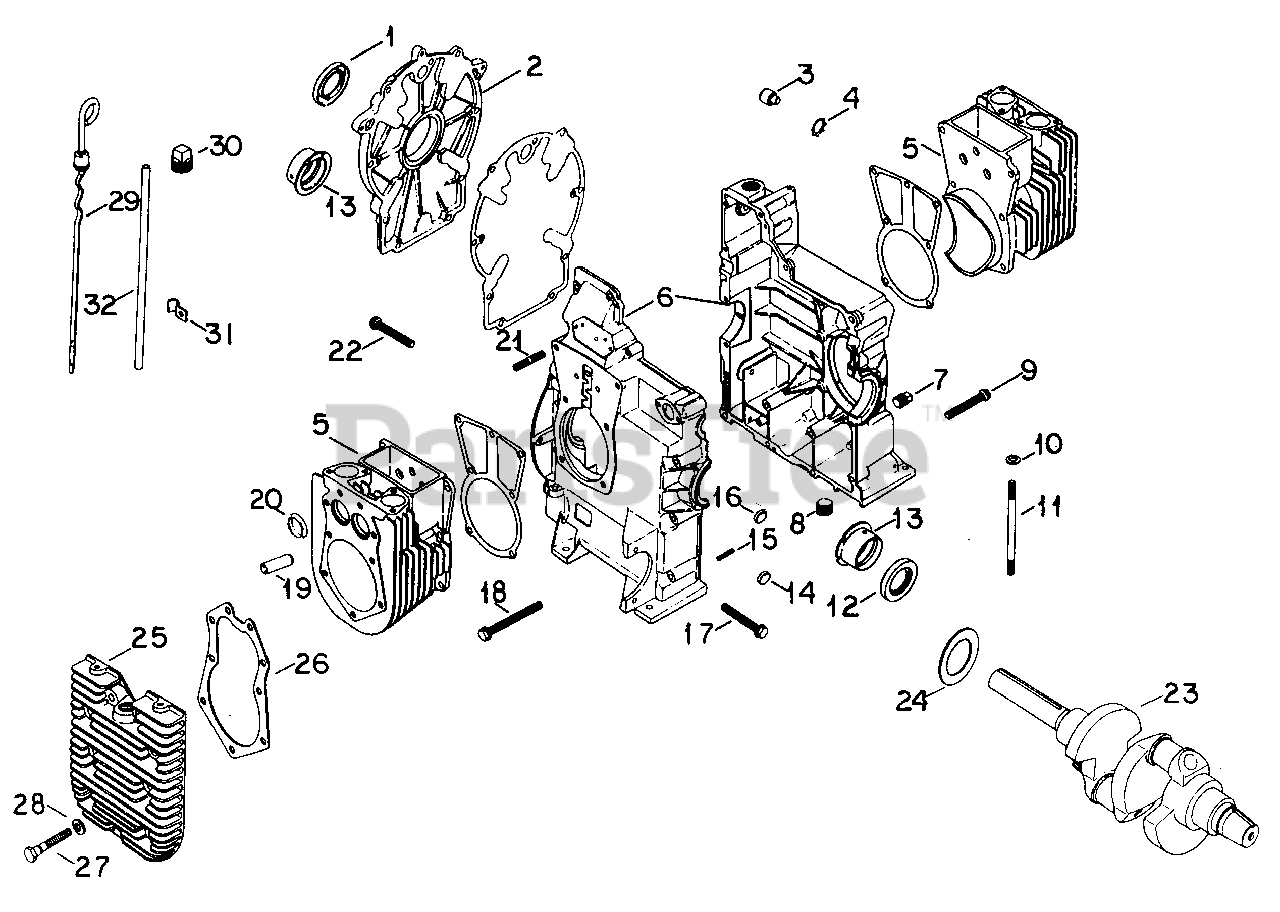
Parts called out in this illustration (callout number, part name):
2	Kit, Closure Plate
3	Shaft, Governor
4	Ring, Retaining
5	Kit, Cylinder
6	Crankcase - Not Serviced Separately
7	Plug, Side Drain, 3/8
8	Plug, Bottom Drain, 3/8
9	Screw, 5/16-18 X 1-1/2 Washer Head
10	Washer, Plain, 21/64
11	Stud, 5/16-18 X 4-1/64
12	Seal, Oil
12	Seal, Front Oil
13	Bearing, Sleeve
13	Bearing, Sleeve, .010 U/S
13	Bearing, Sleeve, .020 U/S
15	Pin, 1/8 X 1-1/4 Slt Spr
17	Screw, 3/8-16 X 3-5/8 Washer Head
18	Screw, 5/16-18 X 3-1/2 Washer Head
19	Guide, Valve
20	Seat, Valve Insert
21	Stud, 3/8-16 X 2
22	Screw, 5/16-18 X 1 Washer Head
23	Crankshaft
24	Washer, Thrust, .123 OR
24	Washer, Thrust, .132 OR
24	Washer, Thrust, .141
25	Head, Cylinder
26	Gasket, Cylinder Head
27	Screw, 5/16-18 X 1-1/2
28	Washer, 5/16
29	Gauge, Oil Dipstick
30	Plug, Oil Fill, 3/4
32	Tube, Oil Dipstick
